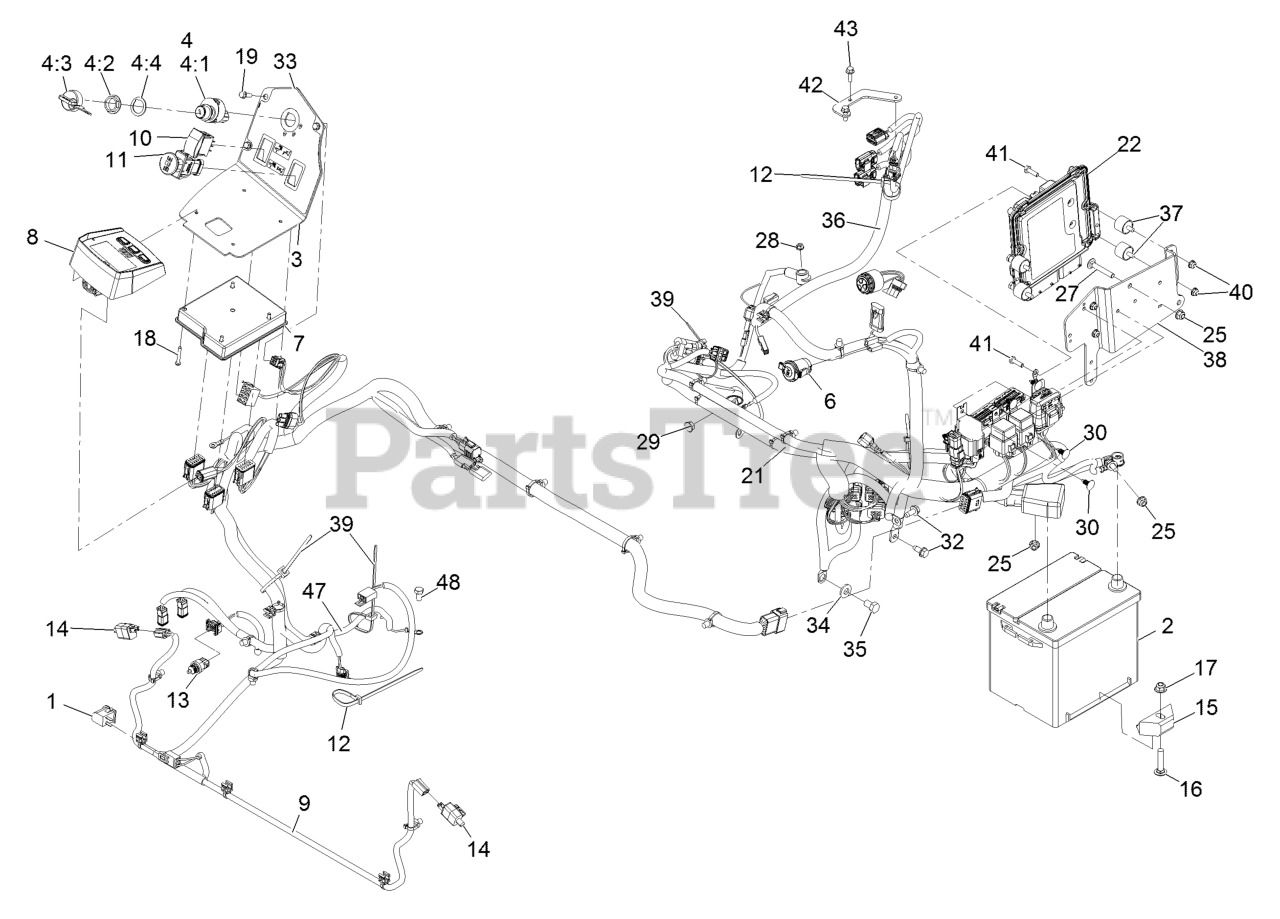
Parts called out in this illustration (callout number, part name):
2	Battery-Dry
3	Plate-Console
4	Ignition Switch ASM
4:1	Switch-Ignition
4:2	Nut-Mounting
4:3	Ignition Key Set
4:4	Washer-Backup
6	Port-Power, 12V
7	Module-Mcu
8	Module, Ldu
9	Harness-Wire
10	Switch, (On)-Off-(On)
11	Switch-PTO, Sealed
12	Tie-Cable 7 15/16 (Large)
13	Sensor-Temperature
15	Retainer-Battery
16	Bolt-Carriage 3/8-16 X 1 3/4
17	Nut-Nyloc 3/8-16 Flg
18	Screw-PPH
19	Screw-Machine 1/4-20 X 3/4
21	Cable-Battery
22	E C U ASM
25	Nut-Nyloc 5/16-18 Flg
27	Bolt-Carriage 3/16-18 X 2
28	Nut-Hex M6-1 Flg
30	Plug-Plastic
32	Screw-HWH 5/16-18 X 3/4 Tf
33	Decal-Control Panel
34	Washer-Spring Disc 3/8
35	Screw-HH
36	Harness-Wire
37	Mount-Cylindrical
38	Mount-Control Unit, Engine
39	Tie-Cable
40	Nut-Nyloc 1/4-20 Flg
41	Screw-HH 1/4-20 X 7/8
42	Bracket-Wiring, Engine
43	Screw-HHF
47	Harness-Wire, Jumper
48	Bolt
